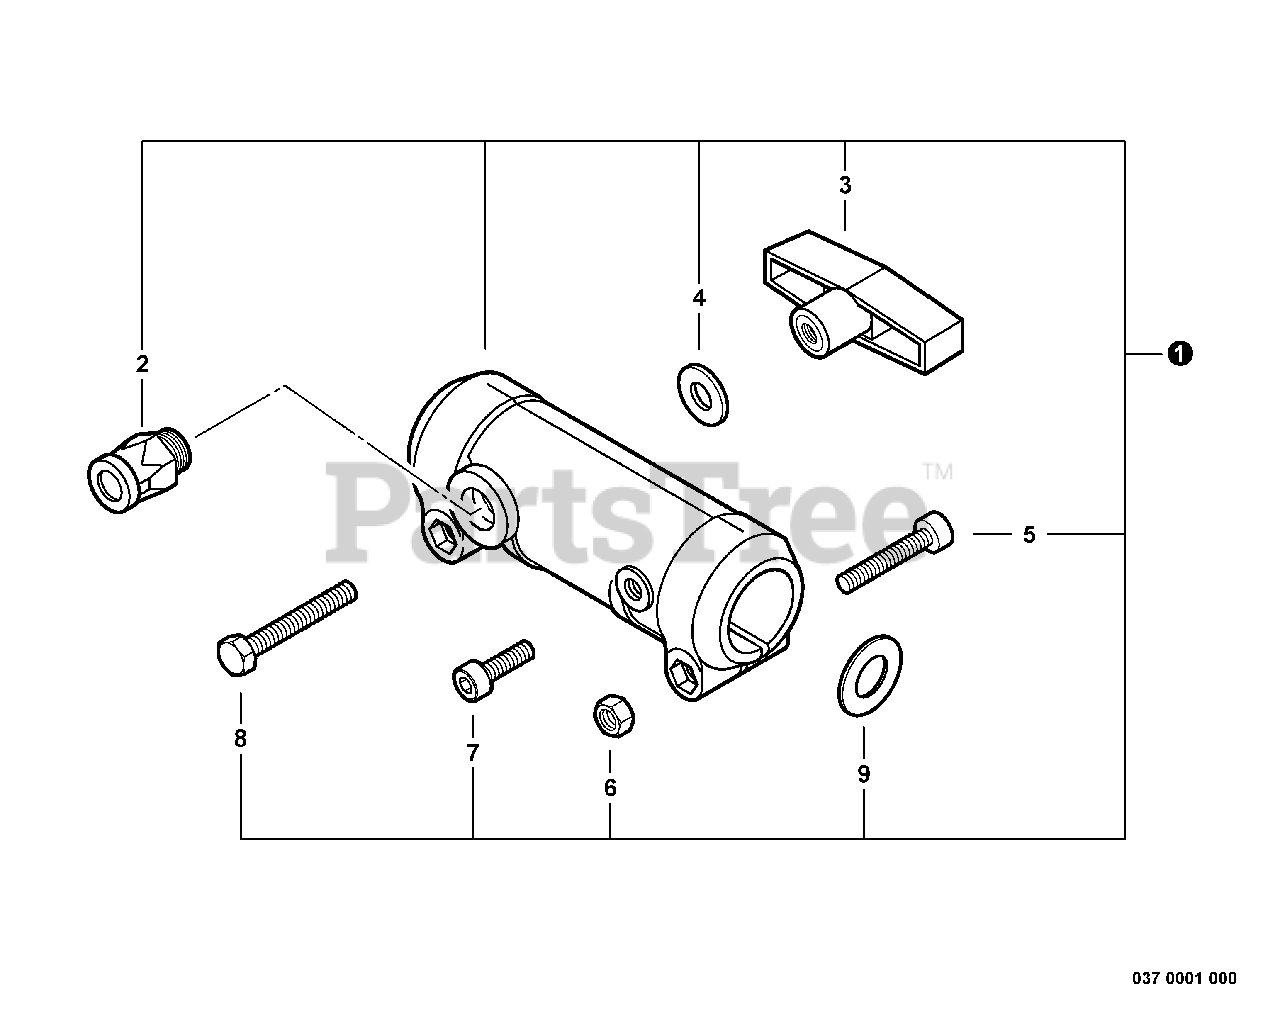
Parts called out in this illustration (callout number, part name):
1	COUPLER ASSY
2	LATCH ASSY
3	KNOB, FASTENER
4	WASHER 6.6×20×1.6
5	BOLT 6×25
7	BOLT M6×10
8	BOLT 6×40
9	WASHER 18 SPR STEEL
